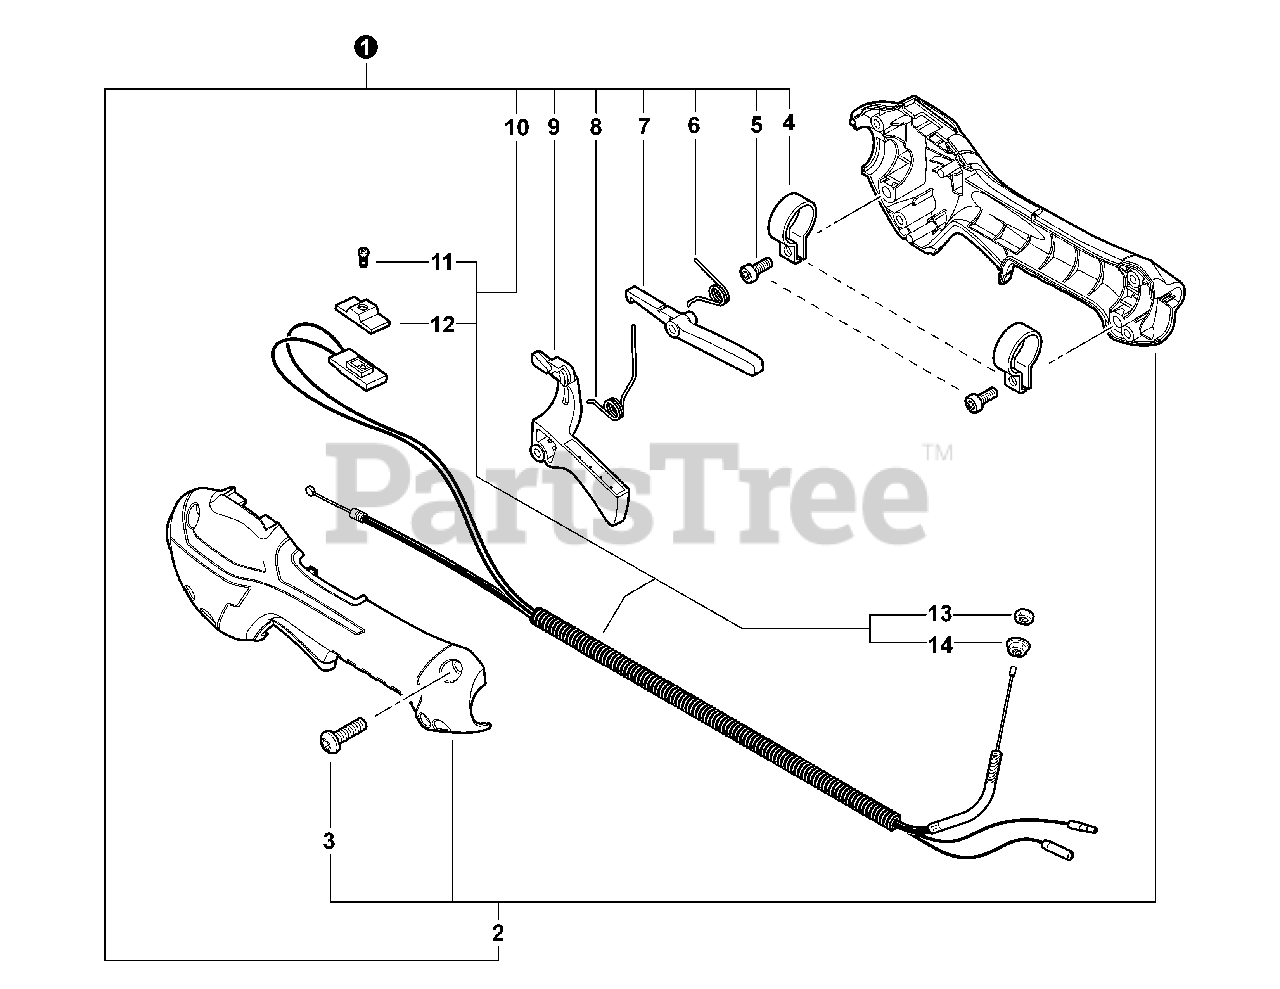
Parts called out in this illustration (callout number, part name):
1	CONTROL HANDLE ASSY
2	CONTROL HANDLE KIT
3	SCREW - 5×16
5	SCREW - 5×16
6	SPRING, LOCKOUT LEVER
7	LEVER, THROTTLE LOCKOUT
8	SPRING, TRIGGER
9	TRIGGER, THROTTLE
10	CONTROL CABLE ASSY
11	SCREW - 3×10
12	KNOB, SWITCH - ORANGE
14	NUT - 6, FLANGE
